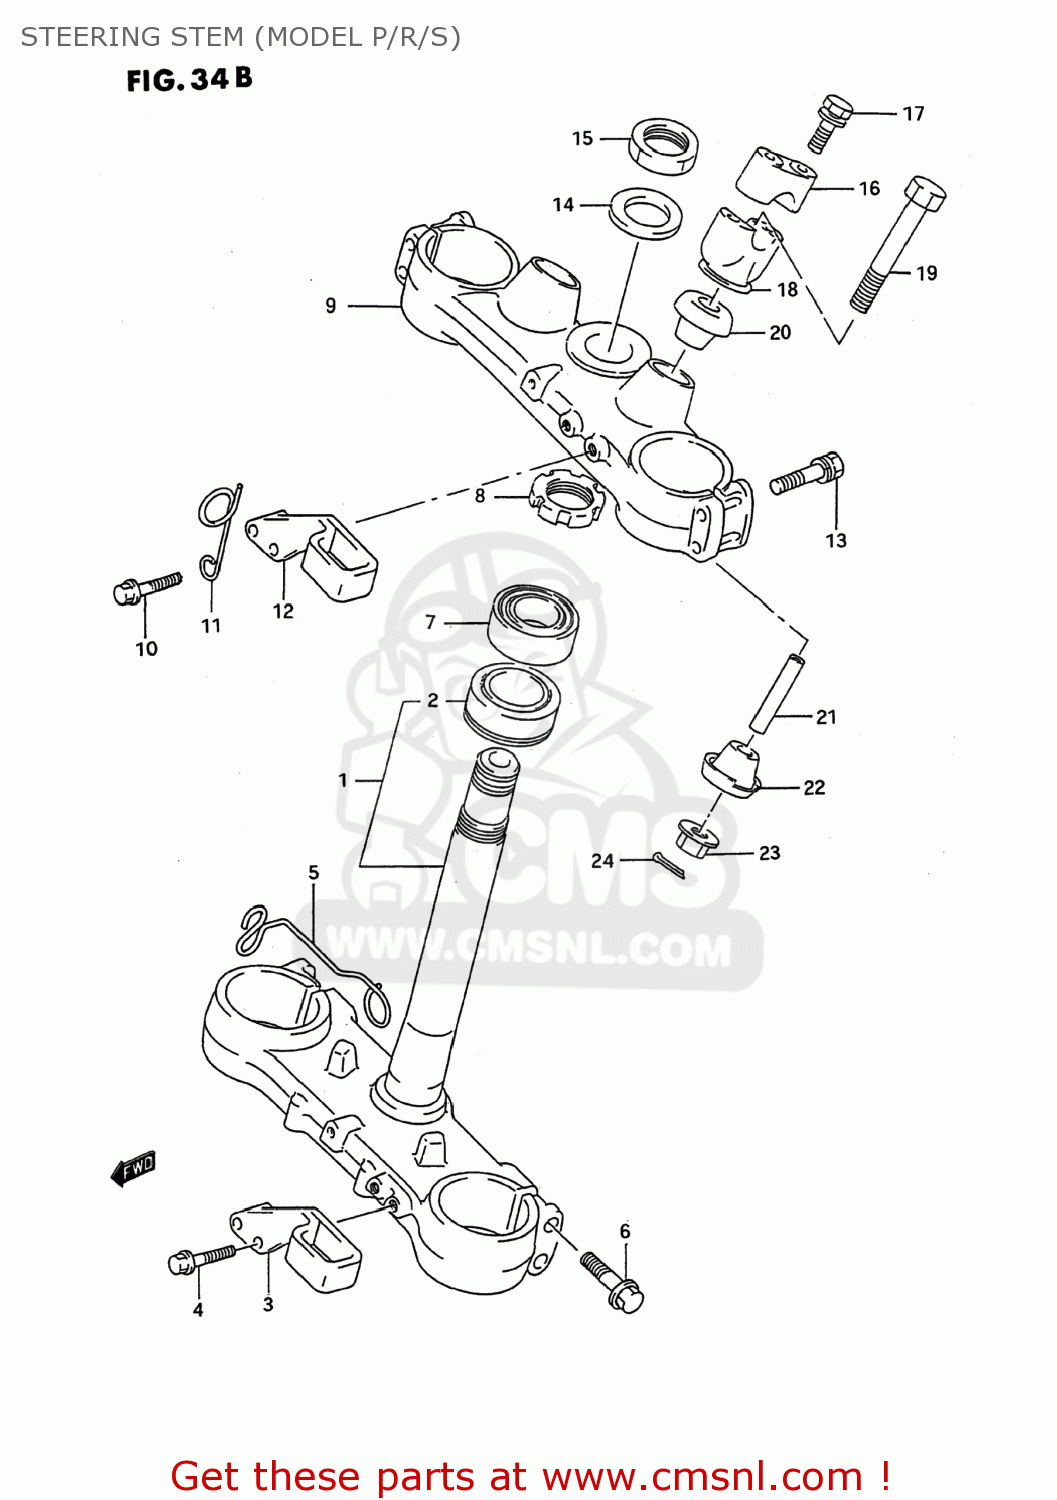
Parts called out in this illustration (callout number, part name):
1	STEM,STEERING
2	BEARING(30X52X16)
3	GUIDE,CLUTCH CABLE
4	BOLT,GUIDE
5	GUIDE,SPEEDOMETER CABLE
6	BOLT,STEM 8X45
7	BEARING(30X52X16)
8	NUT,STEERING
9	HEAD,STEERING STEM
10	BOLT,GUIDE
11	GUIDE,CLUTCH CABLE
12	GUIDE,HOSE
13	BOLT,STEM 8X45
14	WASHER,STEM HEAD
15	NUT,STEM HEAD
16	HOLDER,HANDLEBAR
17	BOLT,HANDLE HOLDER(8X35)
18	HOLDER,HANDLE UNDER
19	BOLT,LWR HOLDER
20	CUSHION,RUBBER UPR
21	SPACER
22	CUSHION,RUBBER UNDER
23	NUT
24	COTTER PIN
